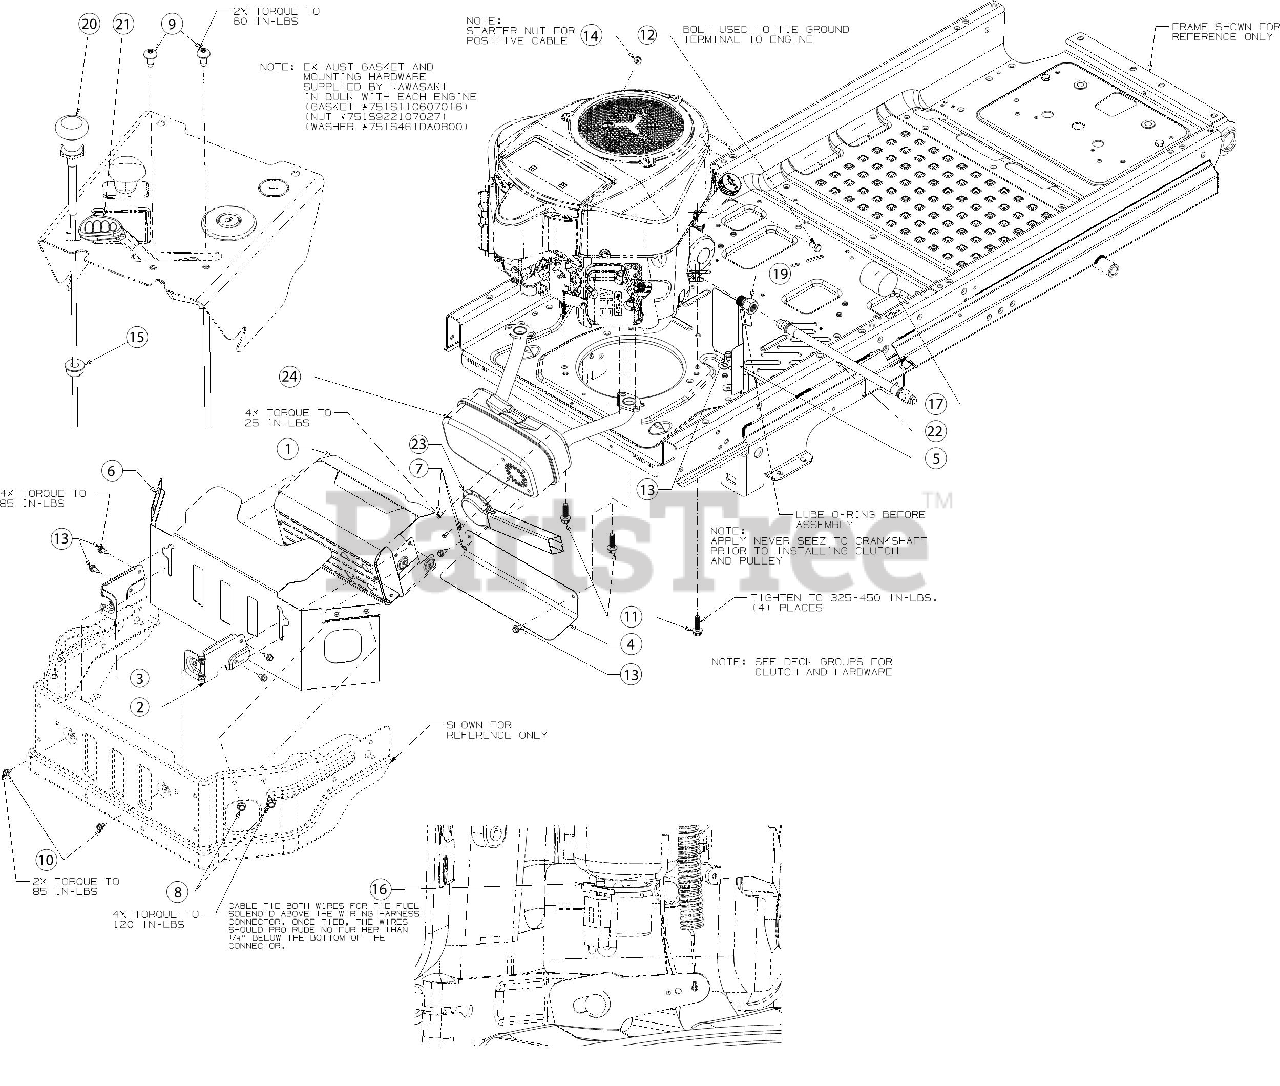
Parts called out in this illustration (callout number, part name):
4	LOWER HEAT SHIELD
5	ENGINE HEAT SHIELD
6	MUFFLER BUMPER SHIELD
7	HEX SCREW WASHER HD #8-18 x 0.500
8	SCREW 5/16-18 x .750
9	SCREW 1/4-20 x .5
10	SCREW 1/4-20 x .375
11	SCREW 3/8-16 X1.250
12	SCREW M8-1.25 x 16 Gr8.8
13	SCREW 1/4-20X.625
14	FLANGE LOCK NUT
15	HEX FLANGE NUT
16	CABLE TIE
19	OIL DRAIN FITTING
20	40.5" CHOKE CABLE
21	THROTTLE CABLE 38.5"
22	OIL DRAIN HOSE
23	MUFFLER DEFLECTOR
24	EXHAUST MUFFLER
